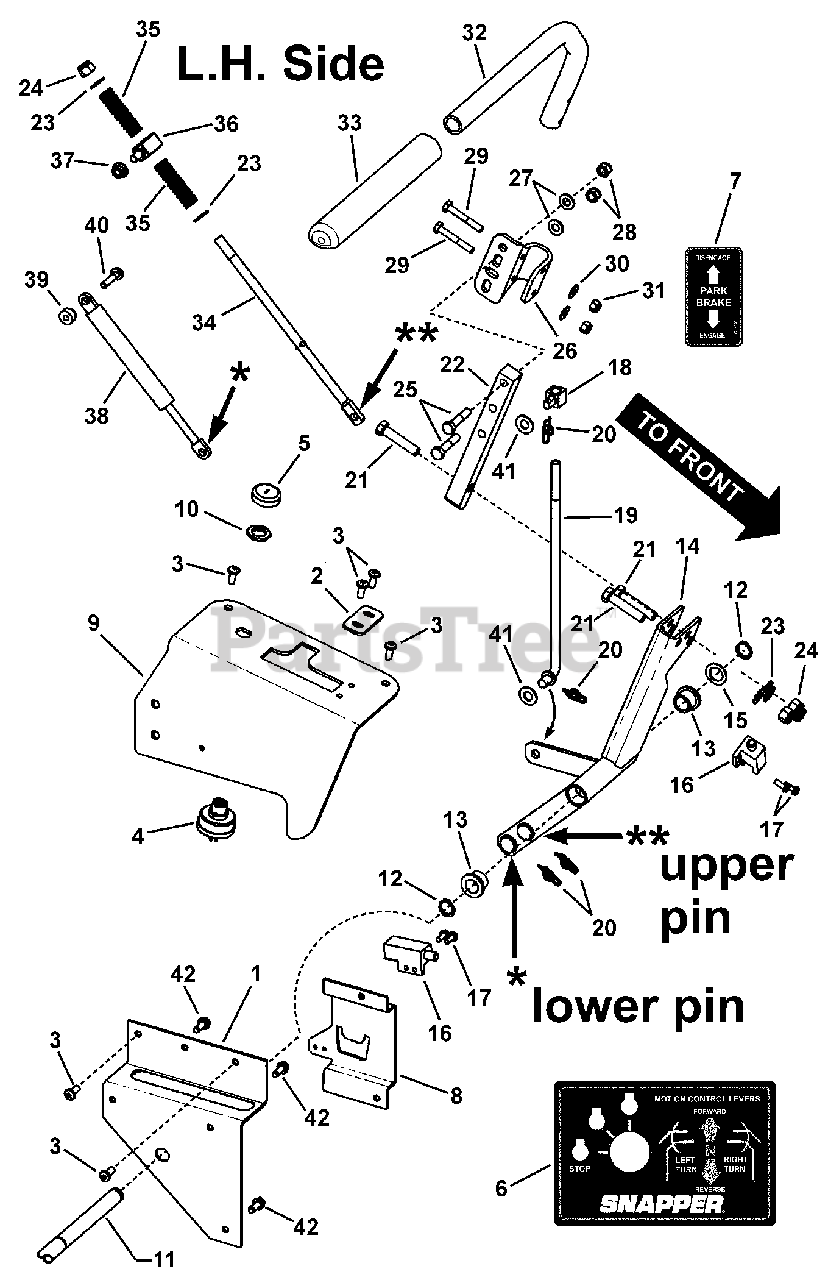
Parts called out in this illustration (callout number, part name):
1	BRACKET, L.H. Tank Support
2	BRACKET, Speed Adjustment
3	SCREW, 1/4-20 x 5/8" Pan Head Self-Tap (Torx)
4	SWITCH, Ignition (After-fire Solenoid)
5	BEZEL
6	DECAL, Ignition Switch
7	DECAL, Park Brake
8	BRACKET, Brake/Clutch Detent, Twin Stick
9	BRACKET, L.H. Console- Twin Stick
10	NUT, 5/8-32 Hex
11	SHAFT, Control, Twin Stick
12	RING, 5/8" External Reatining
13	BUSHING, 5/8 x 5/8" Bronze
14	WELDMENT, Twin Stick, LH
15	WASHER, .64 x .99 x .05 Flat
16	SWITCH, Park Brake (NC/NO)
17	SCREW, #10-24 x 1/2" Hex Washer Self-Tap (Torx)
18	SWIVEL, 3/8-16 Internal Thread
19	CONTROL ROD (3/8-16 thread)
20	PIN, 3/8 Self Locking Cotter
21	SCREW, 3/8-16 x 1-3/4" Hex Head Cap, GR 5
22	BLOCK, Twin Stick Control
23	WASHER, 3/8" Flat
24	NUT, 3/8-16 Hex Nyloc
25	SCREW, 5/16-18 x 1-1/2" Hex Head Cap, GR 5
26	BRACKET, Handle Adjustment
27	WASHER, .34 x .69 x .08 Flat
28	NUT, 5/16-18 Hex Nyloc
29	SCREW, 1/4-20 x 1-3/4" Hex Head Cap, GR 5
30	WASHER, .28 x .63 x .06 Flat, GR 5
31	NUT, 1/4-20 Hex Nyloc
32	HANDLE, Twin Stick
33	GRIP, Twin Stick
34	RETURN ROD (3/8-16 thread)
35	SPRING, Neutral Return
36	SWIVEL, Shoulder (5/16-18 thread)
37	NUT, 5/16-18 Hex Flange Lock, GR 5
38	DAMPENER, Hydraulic
39	SPACER, Twin Stick
40	BOLT, 1/4-20 x 1-1/8" Hex Flange Lock, GR 5
41	WASHER, 3/8" SAE Flat
42	SCREW, 1/4-20 x 5/8" Hex Washer Self-Tap
